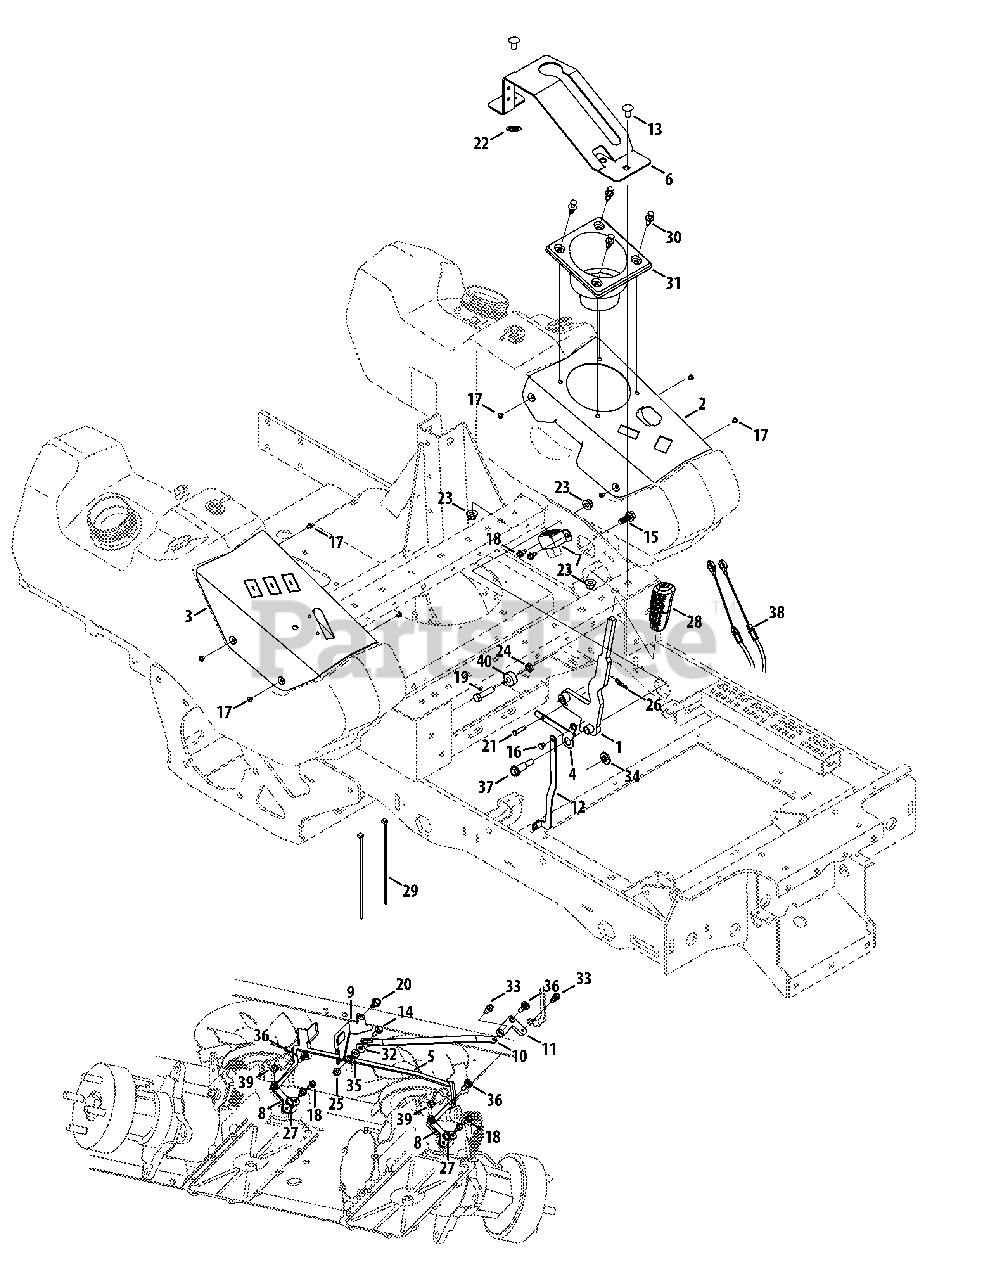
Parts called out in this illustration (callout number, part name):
1	Brake Handle Assembly
2	LH Control Panel
3	RH Control Panel
4	Dump Valve Release Lever
5	Dump Valve Actuator Bracket
6	Boot Brake Bracket
7	Brake Switch Mount
8	Transmission Bypass Lever
9	Neutral Switch Bracket
10	Transmission Actuator Arm
11	Neutral Pivot Control Lever
12	Neutral Arm
13	Carriage Bolt, 3/8-16 x .75
14	Hex Flange Screw, 1/4-20 x .75
15	Screw, 3/8-16 x 1.00
16	Screw, M6 x 8mm
17	Machine Screw, #10-32 x .25
18	Hex Flange Screw, 1/4-20 x .500
19	Hex Cap Screw, 3/8-16 x 1.50
20	Screw, 5/16-18 x .50
21	Clevis Pin, .25 x 1.00
22	Push Nut, 3/8
23	Nut, 3/8-16, Flangelock
24	Jam Nut, 3/8-16
25	Nut, 1/4-20, Hexflange
27	Retainer Ring
28	Grip, .50 ID
29	Cable Tie
30	Rivet, .3125
31	Cup Holder
32	Flat Washer, .283 x .750 x .030
33	Shoulder Screw, .342 x .335, 1/4-28
34	Shoulder Spacer, M6
35	Shoulder Spacer, .375 x .625 x .20
36	Shoulder Screw, .375 x .280, 1/4-14
37	Shoulder Bolt, .50 x .925, 3/8-16
38	Brake Cable
39	Spacer, .256 x .500 x .240
40	Spacer, .406 x 1.00 x .38
